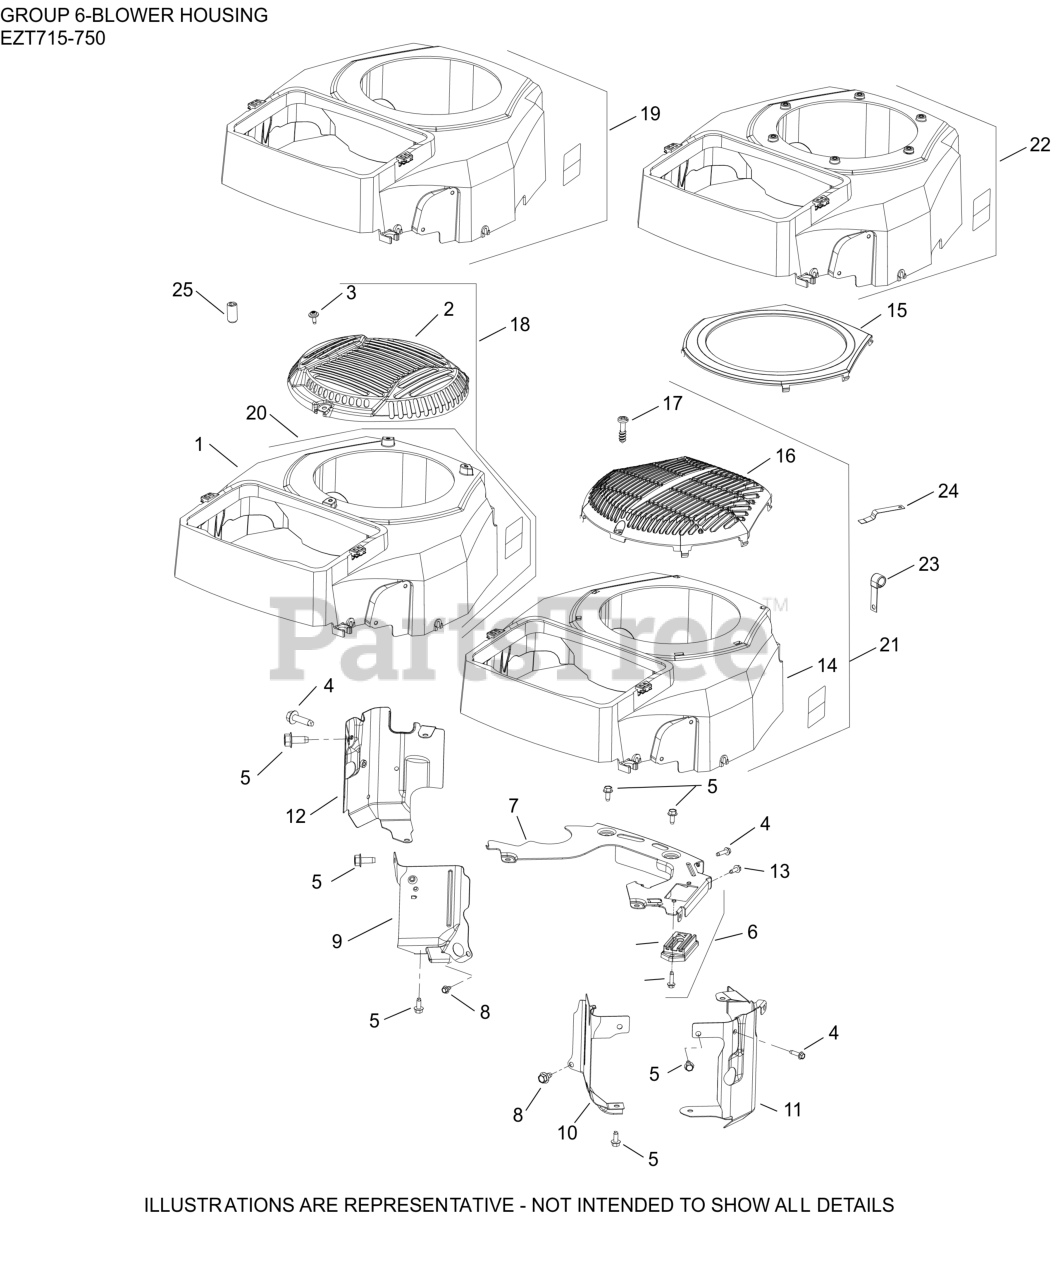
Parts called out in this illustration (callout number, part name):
2	GUARD, GRASS SCREEN (METAL)
3	SCREW, SEMS
4	SCREW, THD FRM-USE 25 086 473-S
5	SCREW, THREAD FORMING
6	PLATE ASSEMBLY, BACKING (15A)
7	PLATE, BACKING
8	SCREW, THREAD FORMING
9	BAFFLE, VALLEY #1
10	BAFFLE, VALLEY #2
11	BAFFLE, LEFT BARREL
12	BAFFLE, RIGHT BARREL
13	SCREW, THREAD FORMING
NI	KIT, BLOWER HOUSING
